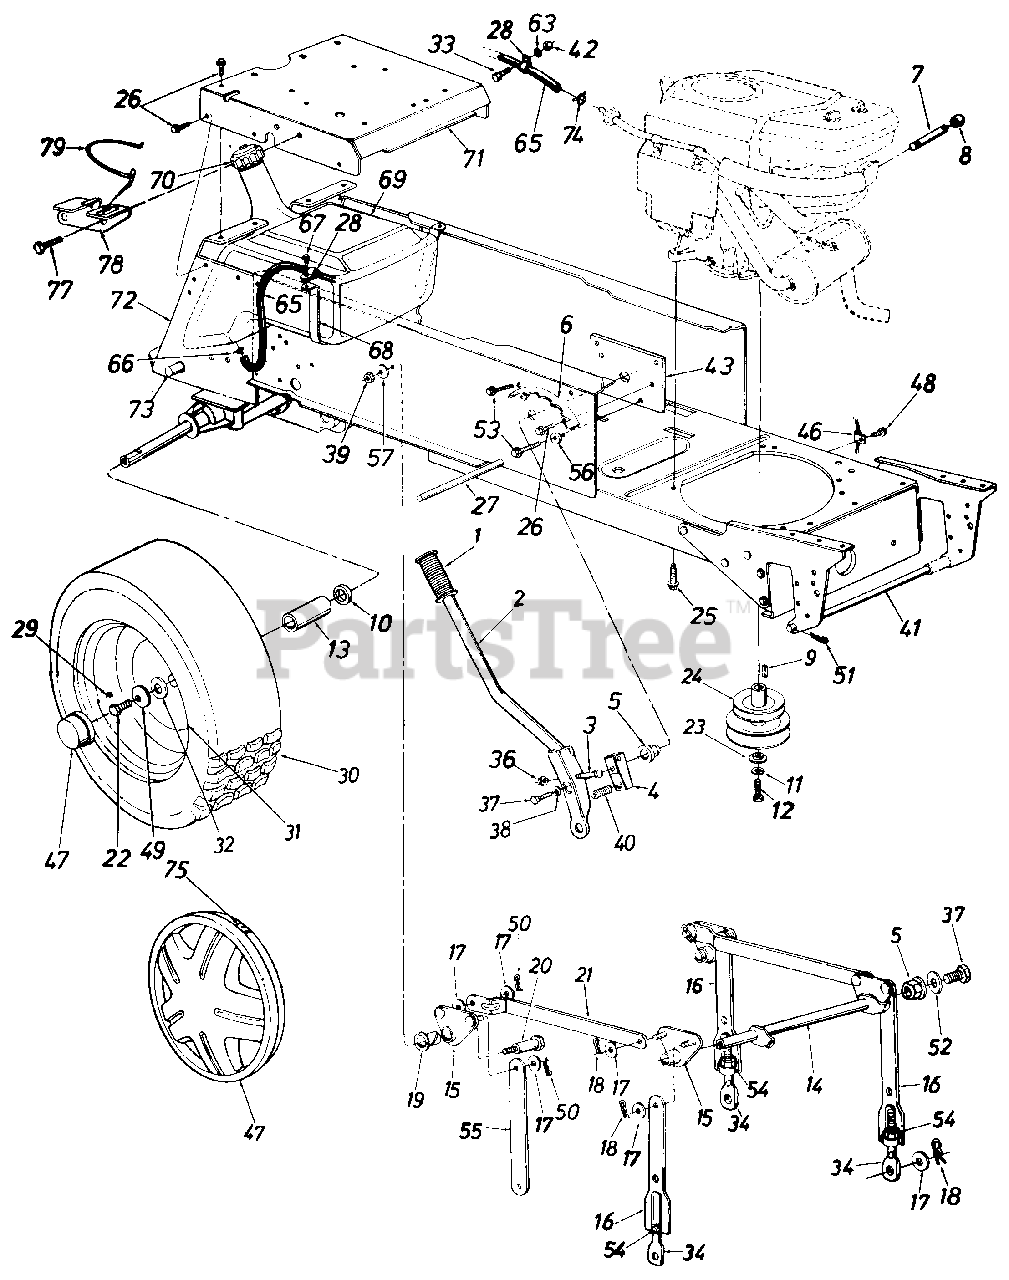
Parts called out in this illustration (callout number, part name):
1	Grip
2	Lift Handle Ass'y.
3	Hex Bolt 5/16-18 x 1.5" Lg.
4	Lift Shaft Drive
5	Plastic Hex Brg. 518" I.D.
8	Pipe Cap 3/8-18 Npt.
9	Sq. Key 1/4" x 1/4" x 1.50" Lg.
10	Fl-Wash. .76" I.D. x 1.49" O.D.
11	L-Wash. 7/16" I.D.
12	Hex Scr. 7/16-20 x 1.50" Lg.
13	Sleeve .75" I.D. x 1 O.D.
14	Lift Shaft Ass'y.
15	Lift Pivot Brkt. Ass'y.
17	Fl-Wash. 1/2" I.D. x 1.00" O.D. x .090"
18	Hairpin Cotter
19	Nyliner 5/8" I.D. x .88" Lg.
20	Shld. Bolt 5/8" Dia. x .96" Lg. 3/8-16
23	Flat Wash. .44" I.D. x 1.25" O.D. x .17"
24	Two-Step Engine Pulley
25	Hex Wash. Hd. Scr. 3/8-16 x 1.25" Lg.
26	Hex Thd. Rolling Scr. 5/16-18 x.75" Lg.
27	Running Board Rod
28	Clamp
29	Air Valve
30	Rear Wheel Ass'y. Comp.
31	Rear Wheel Rim Only
32	Flat Wash. .34" I.D. x 2" O.D.
33	Hex Bolt 1/4-20 x .62" Lg.
34	Eye Bolt Adj. Link 1/2-13 Thd.
36	Hex Cent. L-Nut 5/16-18 Thd.
37	Hex Bolt 5/16-24 x .62" Lg.
38	L-Wash. 5/16" I.D.
39	Hex Top L-Nut 3/8-16 Thd.
40	Compression Spring
41	Deck Connecting Rod
42	Hex Nut 1/4-20 Thd.
47	Hub Cap
48	Hex Wash. Hd. TT-Tap Scr. '/4-20 x .5" Lg.
49	Bell-Wash...39" I.D.
50	Cotter Pin .09 Dia. x 1.0" Lg.
51	Int. Cotter Pin
52	Flat Wash. .34" I.D. x 1.12" O.D. x .125"
53	Hex Wash. Hd. AB-Tap Scr. 5/16-24 x .5" Lg.
54	Hex Nut 1/2-13 Thd.
56	Fl-Wash. .344" I.D.
57	Bell-Wash. .4" I.D. x 1.13" O.D.
63	L-Wash. 1/4" I.D.
65	Fuel Line 50" Lg.
66	Hose Clamp
67	Hex AB-Tap Scr. 1/4 x .62" Lg.
68	Fuel Tank Strap
69	Gas Tank
70	Gas Gauge
71	Seat Plate
72	Hitch Plate
73	Hitch Rod
74	Hose Clamp
75	Spring Clip
77	Hex Wash. Hd. TT-Tap Scr. 5/16-18 x .62" Lg.
78	Speed Control Brkt.
79	Comp. Spring Clip
